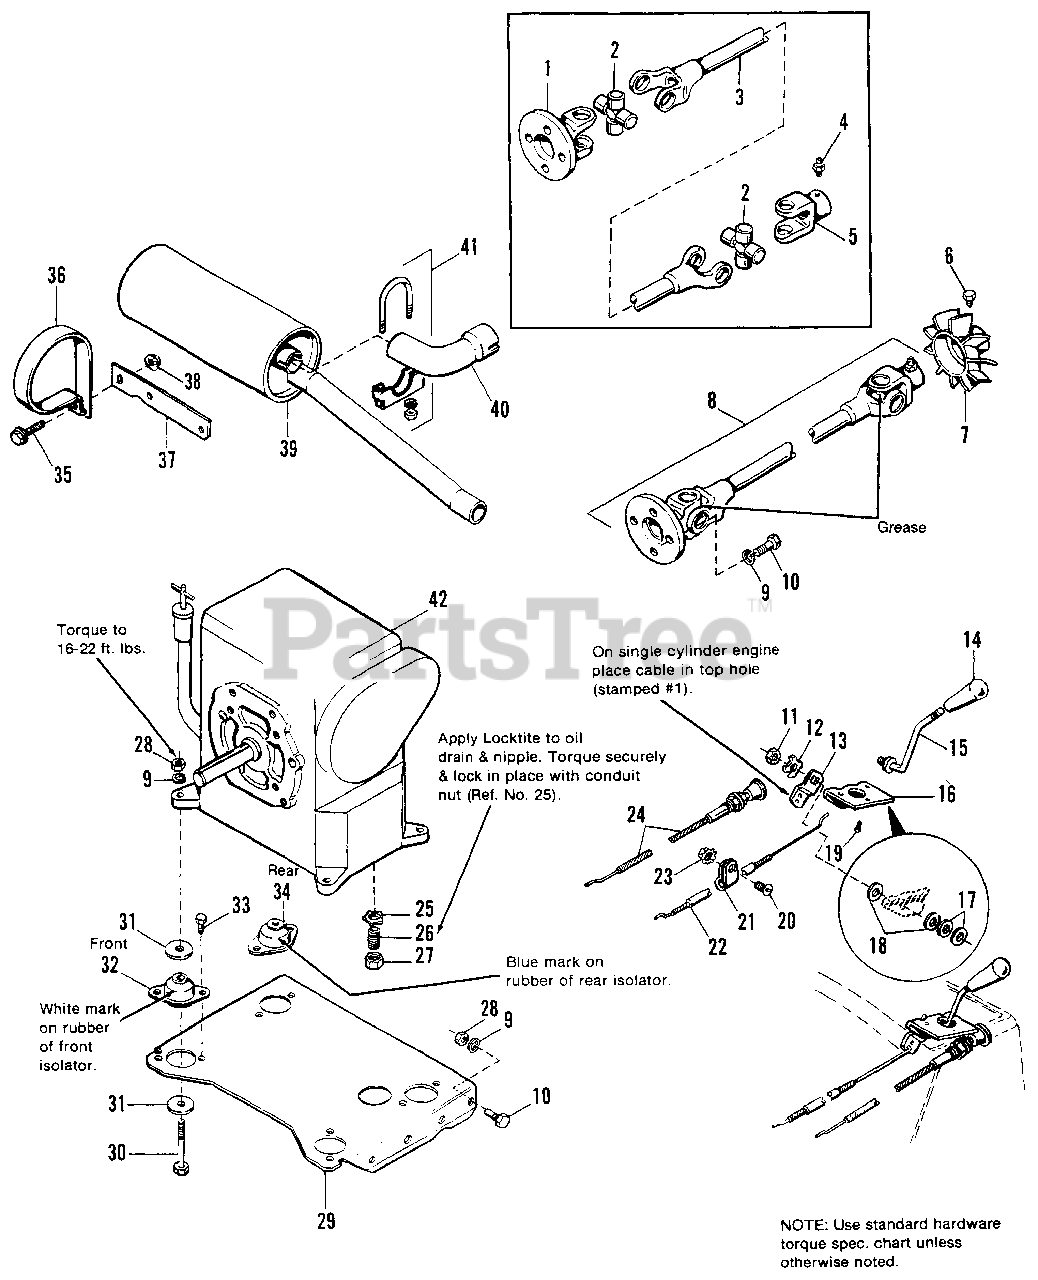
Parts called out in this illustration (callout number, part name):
2	JOURNAL ASSY.
3	SECTION, Cover
4	FITTING, Lube
6	SCREW, Taptite, #10-32 x 3/8
7	FAN, Hydro Pump
8	DRIVESHAFT ASSY.
9	LOCKWASHER, Spring, 3/8
10	CAPSCREW, Hex Hd., 3/8-16 x 1
11	LOCK NUT, Hex, 3/8-16
12	LOCKWASHER, Dished Type,3/8
13	ARM, Throttle
14	KNOB, Throttle, 3/8-16 UNC
15	HANDLE, Throttle
16	BRACKET, Mtg., Throttle Control
17	WASHER, Plain, 5/8 I.D. x 1" O.D.
18	WASHER, Nylon, 41/64 I.D. x 1" O.D. x 1/32
19	SCREW, Slotted Hex Hd., Plastite 1/4-20 x 5/8
20	SCREW, Phillips, Truss Hd. #10-32 x 1/2
21	CLIP, Bowden Wire
22	CABLE, Throttle
23	NUT & WASHER ASSY., Keps #10-32
24	CONTROL, Choke
25	NUT, Conduit, 3/8-18
26	NIPPLE, Pipe, 3/8 x 1
27	CAP, Hex, 3/8-18 NPT
28	NUT, Hex, 3/8-16
29	PLATE, Engine Base
30	CAPSCREW, Hex. Hd., 3/8-16 x 2-3/4
31	WASHER, Plain, 13/32 I.D., 1-27/32 O.D.
32	ISOLATOR, Engine Mount (Front)
33	SCREW, Taptite, 5/16-18 x 1/2
34	ISOLATOR, Engine Mount, (Rear)
35	CAPSCREW, Hex Whiz, Flange, 5/16-18 x 1-1/2
36	CLAMP, Muffler
37	STRAP, Mtg., Muffler
38	NUT, Hex Flange, 5/16-18
39	MUFFLER, Exhaust
40	ELBOW, Exhaust
41	CLAMP, Exhaust
42	ENGINE, 14 HP Kohler ENGINE, 16 HP Kohler
